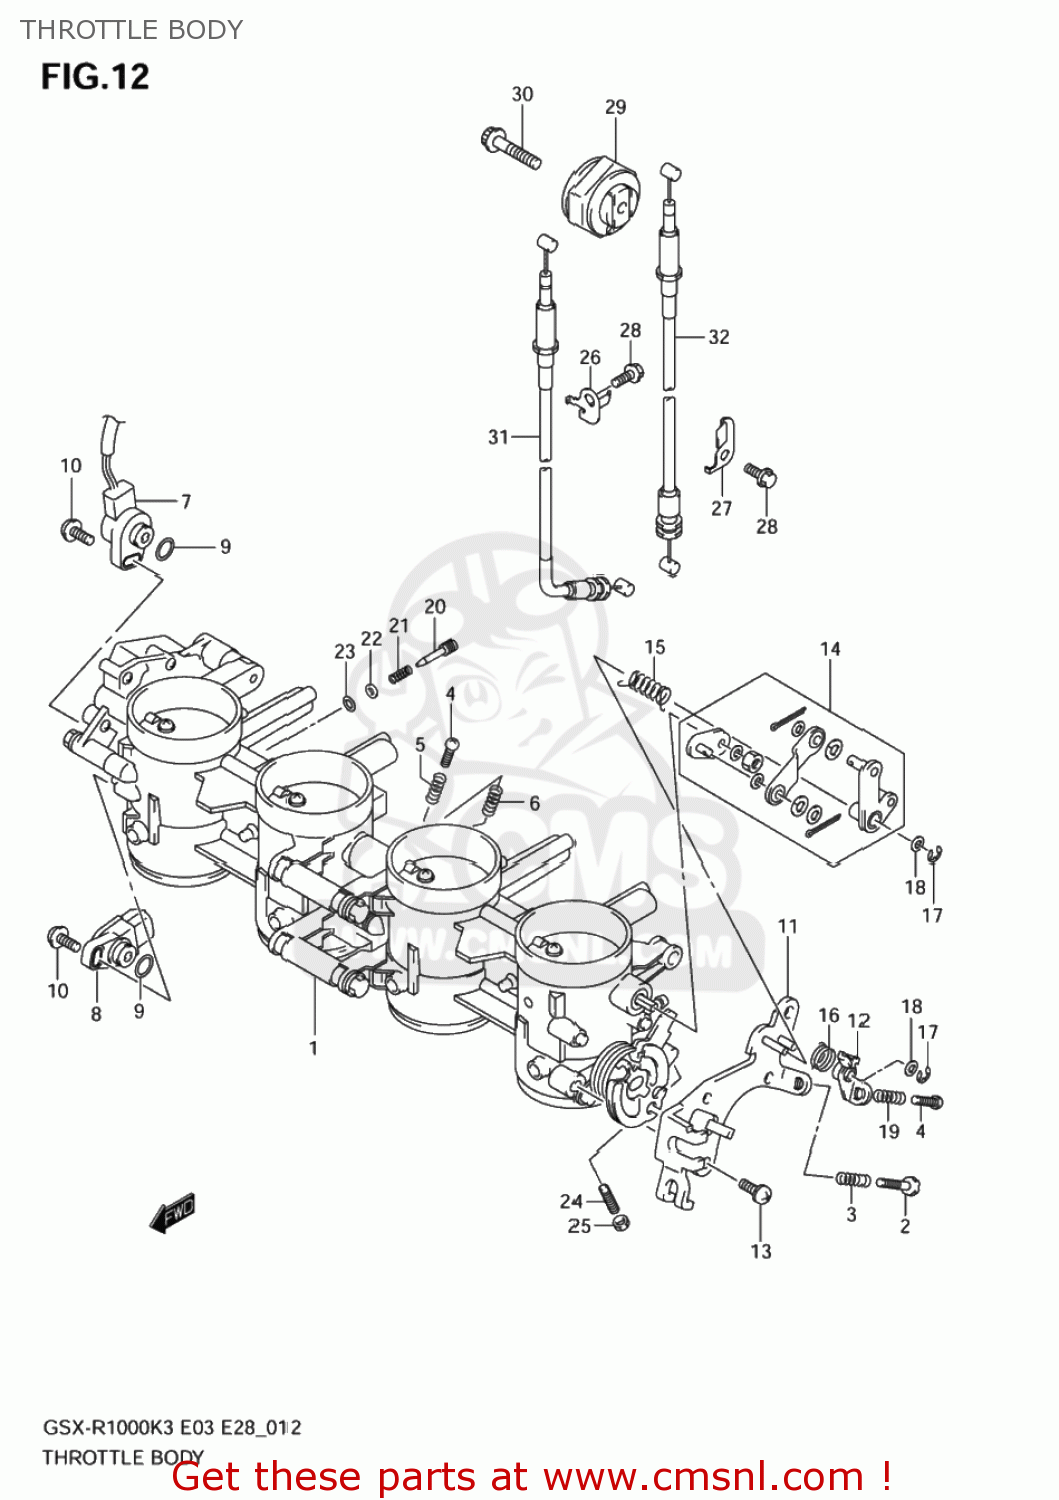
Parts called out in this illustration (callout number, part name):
1	BODY ASSY,THROTTLE
2	SCREW,STOP
3	SPRING
4	SCREW,STOP
5	SPRING
6	SPRING
7	SENSOR ASSY,TH
8	SENSOR ASSY,THROTTLE MAIN
9	O RING
10	SCREW
11	PLATE,STAY
12	LEVER,LINK
13	SCREW
14	LEVER SET,LINK
15	SPRING
16	SPRING
17	E CLIP
18	WASHER
19	SPRING
20	SCREW,AIR ADJUST
21	SPRING
22	WASHER
23	O RING
24	SCREW,STOP
25	NUT
26	BRACKET,EXHAUST VALVE CABLE UP
27	BRACKET,EXH VALVE CABLE LOW
28	BOLT
29	PULLEY CONTROL
30	BOLT
31	CABLE,EXHAUST VALVE NO.1
32	CABLE,EXHAUST VALVE NO.2
